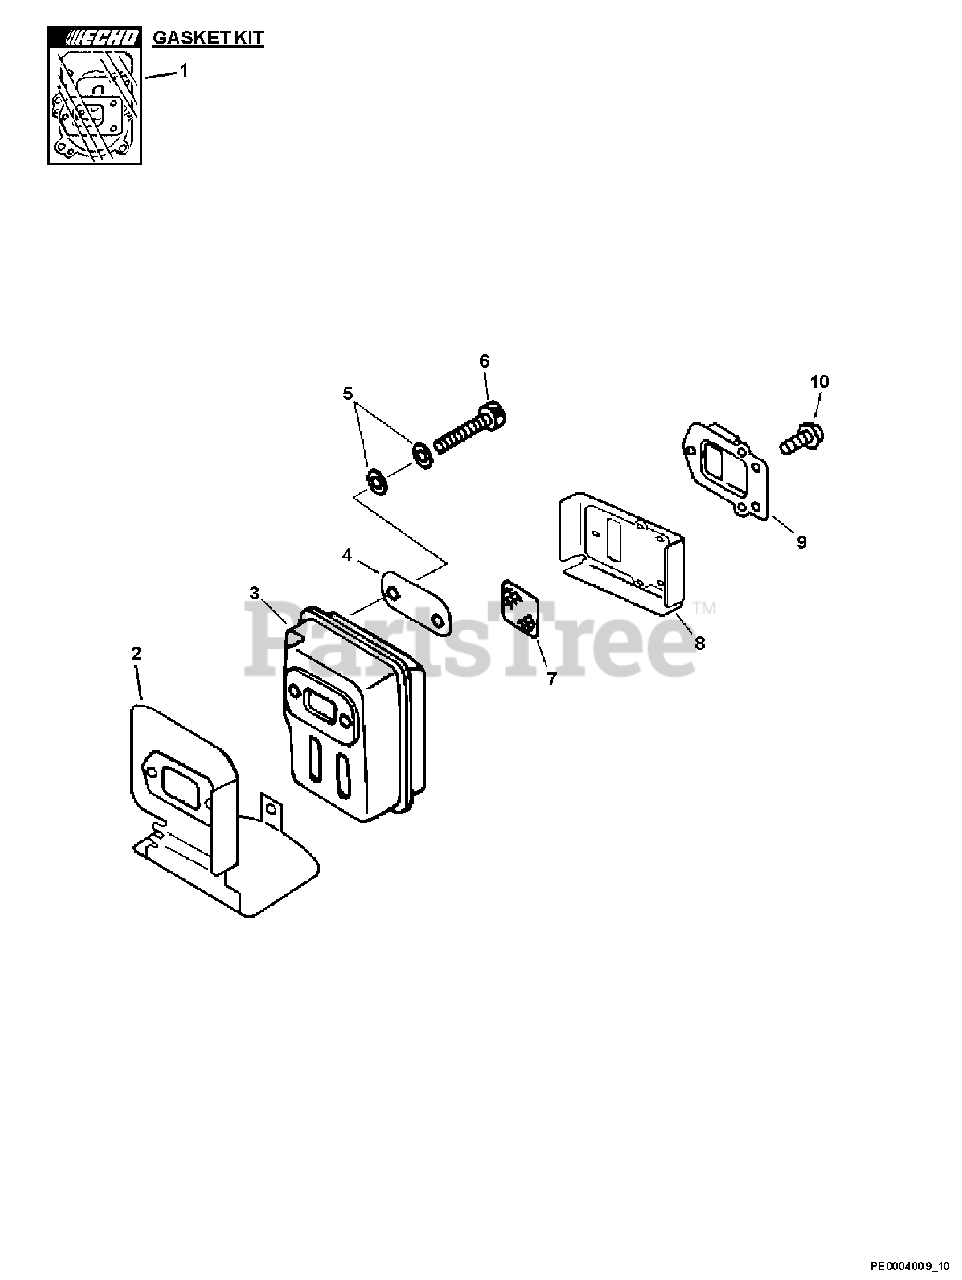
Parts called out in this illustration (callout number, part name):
1	GASKET KIT
2	SHIELD, EXHAUST
3	MUFFLER
5	WASHER - CONICAL
6	SCREW - 5X55
7	SCREEN, SPARK ARRESTOR
8	GASKET, EXHAUST
9	GUIDE, EXHAUST
10	SCREW - 4X12
